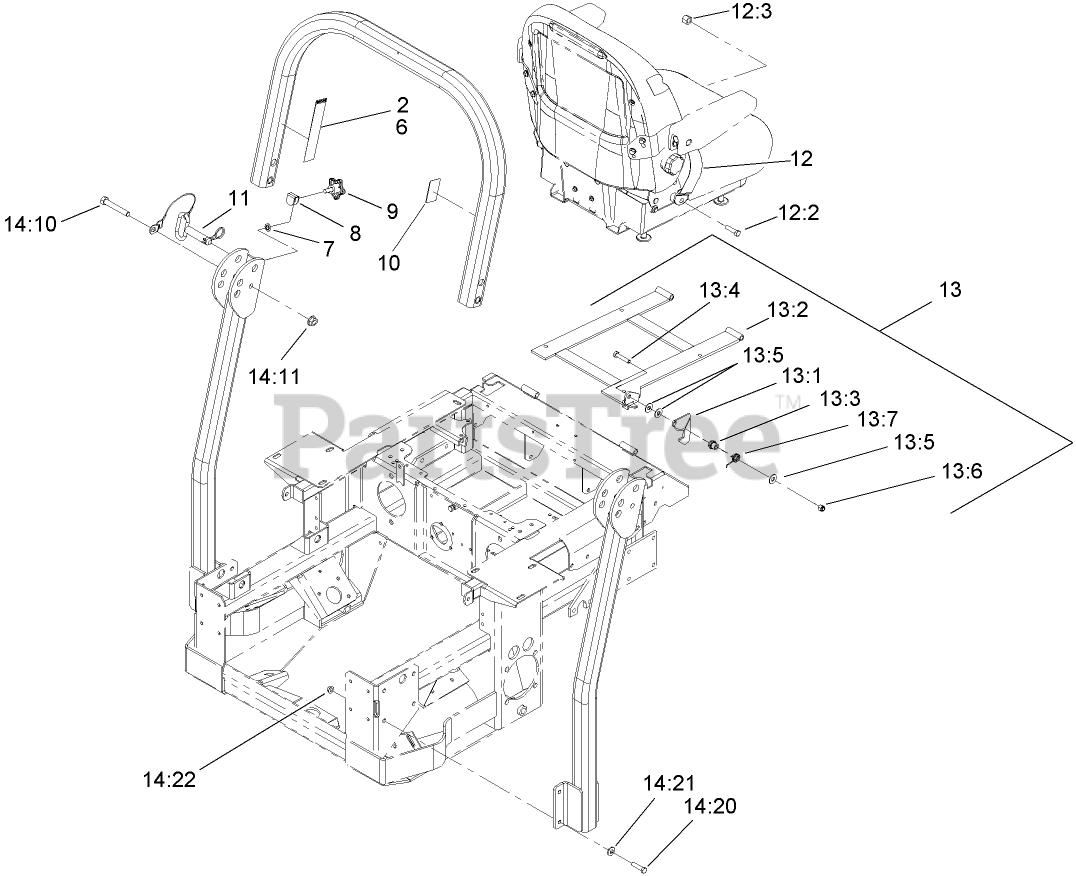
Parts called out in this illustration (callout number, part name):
2	DECAL-WARNING, FOLDING ROPS
6	DECAL-WARNING
7	NUT-PUSH
10	DECAL-ROPS
11	PIN-FOLD, ROPS
12	SEATBELT KIT
12:2	SCREW-HH
12:3	NUT-LOCK, NI
13	SEAT FRAME ASM
13:1	CATCH-LATCH, SINGLE
13:3	BUSHING-LATCH, SEAT
13:4	SCREW-HH
13:5	WASHER-FLAT
13:6	NUT-LOCK, NI
13:7	SPRING-TORSION, LATCH
14	BAG-BOLT
14:10	SCREW-HH
14:11	NUT-HF
14:20	SCREW-HH
14:21	WASHER-BELLEVILLE
14:22	NUT-HHF, WHIZ
